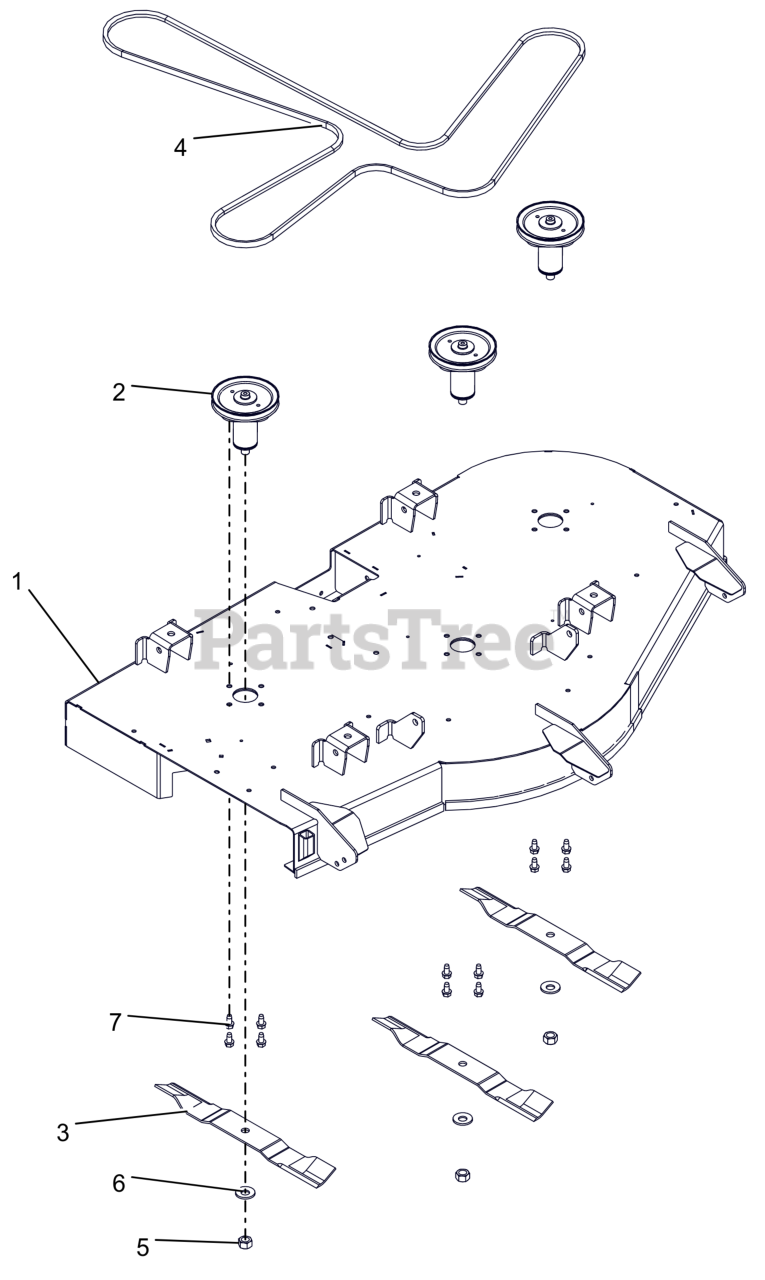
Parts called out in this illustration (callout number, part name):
1	KIT, 52" ARIENS DECK W/DECALS
2	KIT, DECK SPINDLE ASM-52
3	BLADE, 18" - 30 DEG .5 OFFSET
4	V-BELT, HA-WRAPPED
5	NUT-STD .625-18 ZCC
6	WSHR-BLVL .669X1.535X.138
7	SCR,TAP .375-16X.75 HWH TR ZCC
